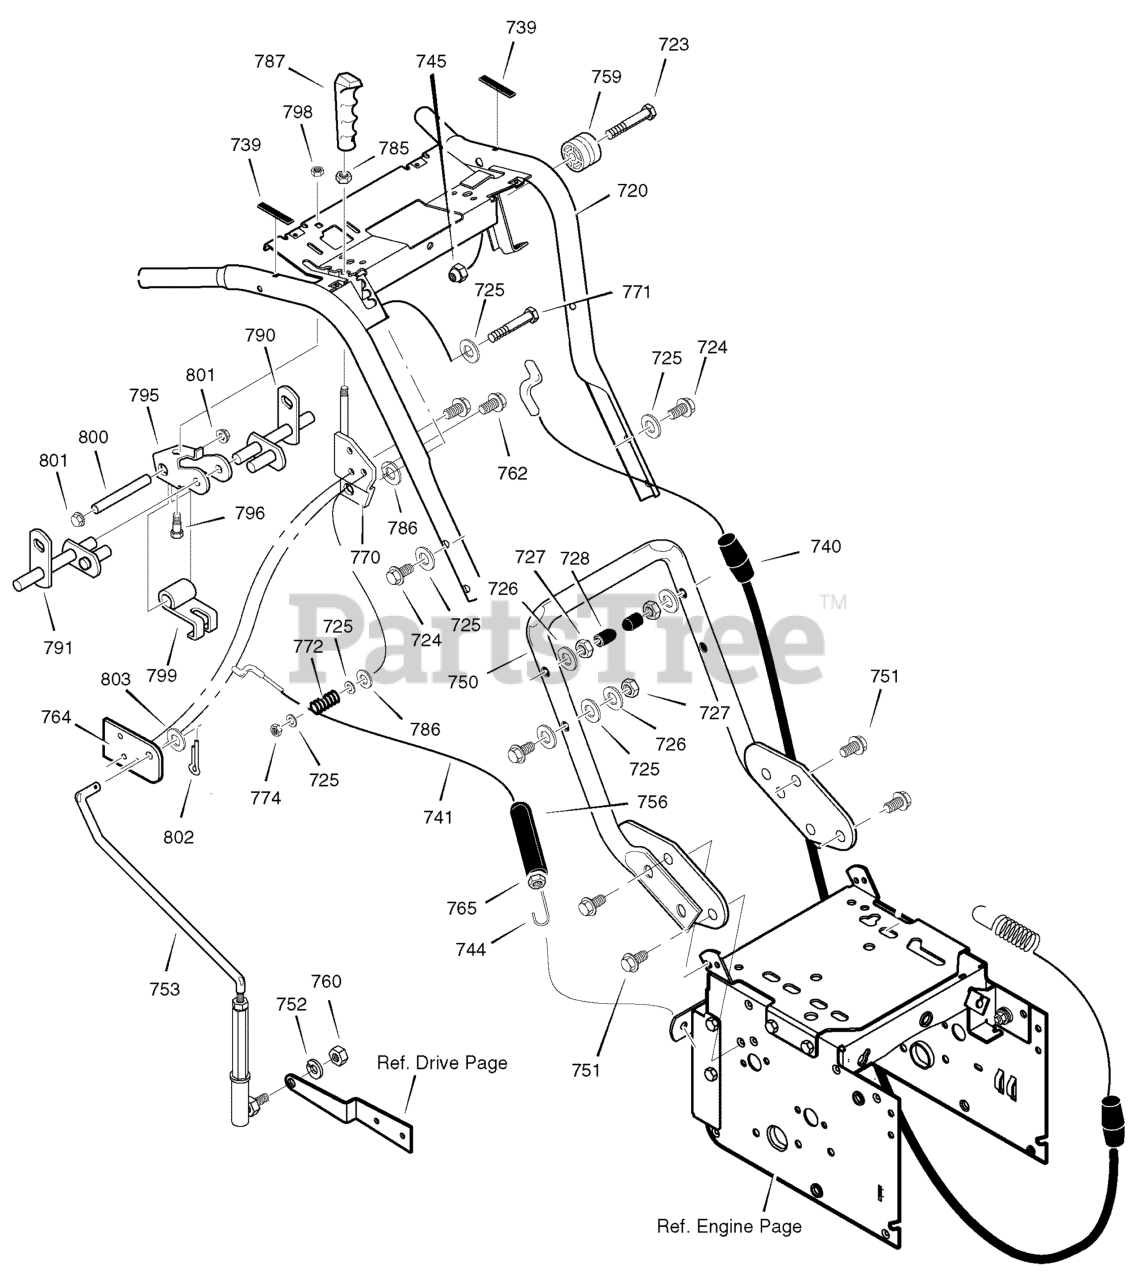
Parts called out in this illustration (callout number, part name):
720	ASSY., HANDLE
728	STOP, PLASTIC
739	BUMPER
740	CABLE, DRIVE
741	CABLE, AUGER
744	SPRING, AUGER CLUTCH
745	NUT, HEX -- 1/4--20
750	HANDLE, LOWER
753	ASSEMBLY, ROD
756	BOOT, SPRING
759	SPOOL, CABLE
760	NUT, 5/16--24
762	SCREW 1/4--20X0.63
764	BRACKET, CONTROL
765	NUT, HEX -- 1/4--20
770	BRACKET, SHIFT
774	NUT, HEX, 3/8--16
785	NUT, HEX, 3/8--16
787	GRIP, LEVER
790	ROD, ASSY LH
791	ROD, ASSY RH
795	BRACKET, CAM
798	NUT, NYLOCK
799	CAM LOCK
800	PIN, SPRING PIVOT
801	NUT, PUSH ON
802	PIN, COTTER
